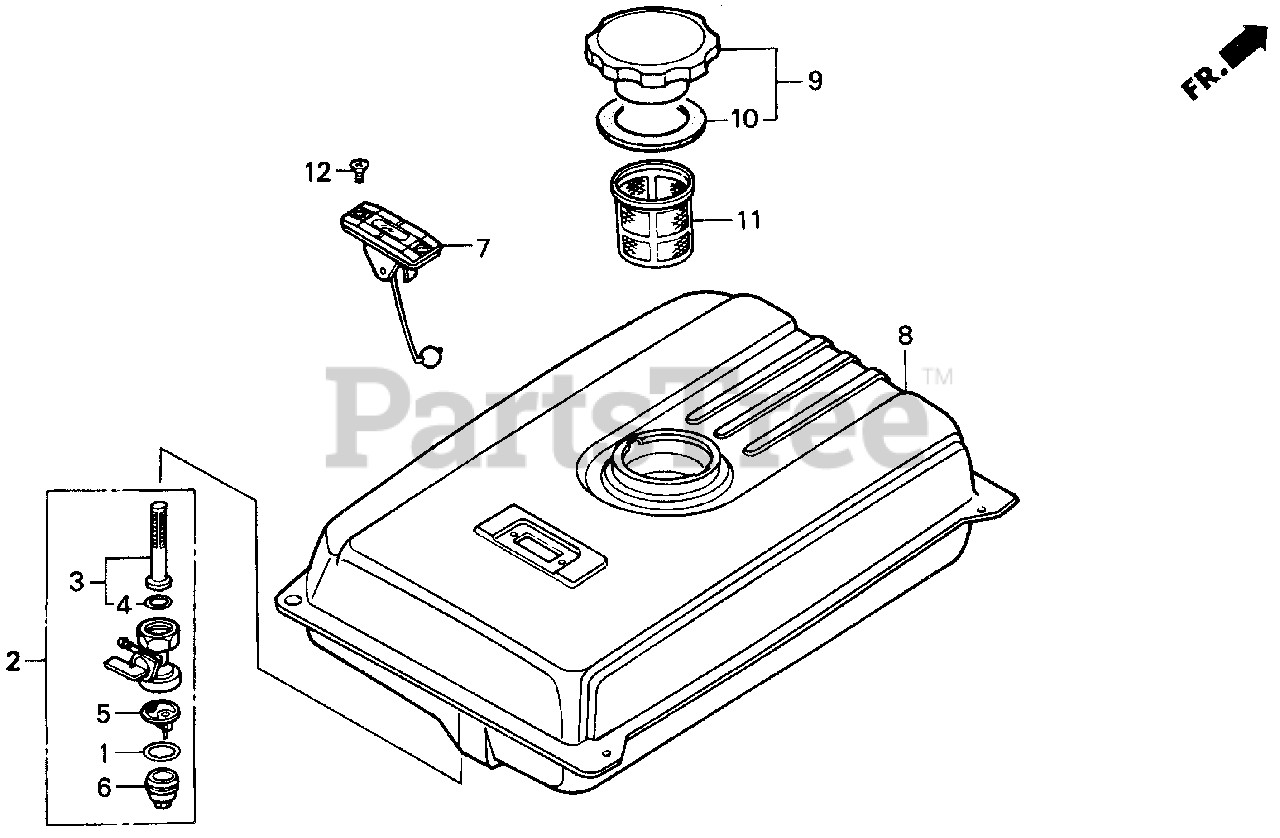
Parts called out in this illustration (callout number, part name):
1	GASKET, FUEL STRAINER CUP
2	PETCOCK ASSY.
3	SCREEN, FUEL STRAINER
4	O-RING (9X1.3)
5	FILTER, CUP
6	CUP, FUEL STRAINER
7	METER ASSY., FUEL
8	TANK, FUEL *NH31* (MCKINLEY WHITE)
9	CAP, FUEL TANK
10	GASKET, FUEL FILLER CAP
11	FILTER, FUEL
12	SCREW, FLAT (5X10)
